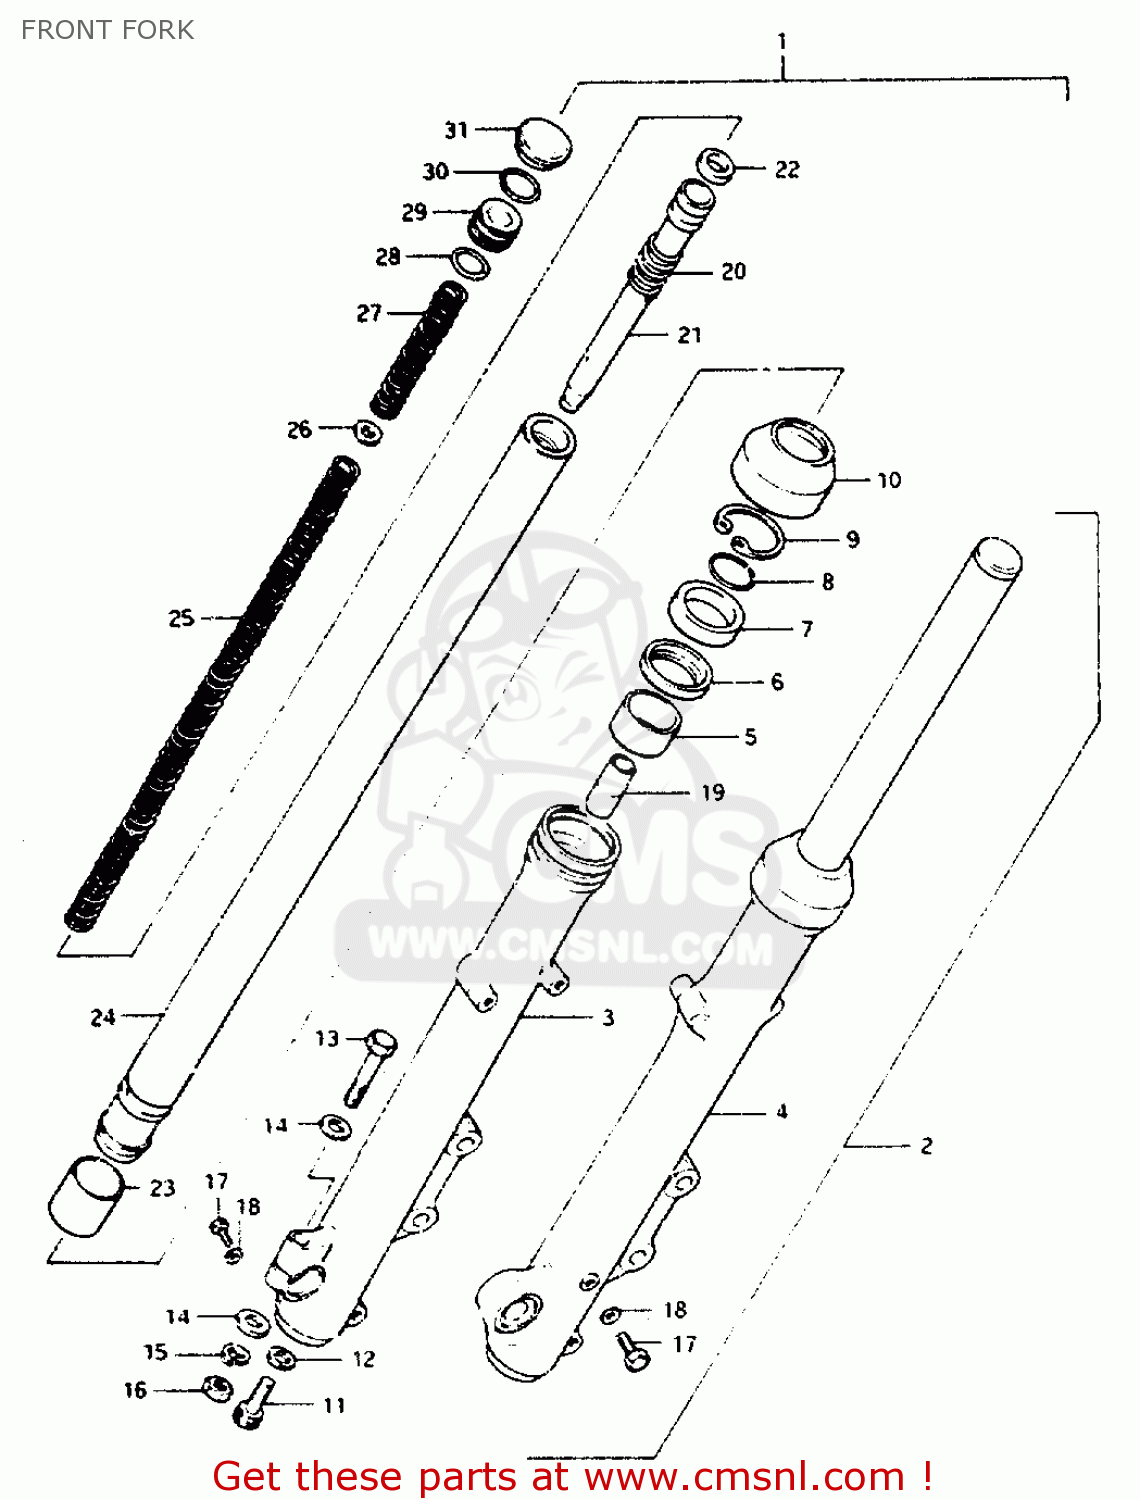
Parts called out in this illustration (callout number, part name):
1	DUMPER ASSY, RH
2	DUMPER ASSY, LH
3	TUBE,FORK,OUTER,RIGHT
4	TUBE,FORK,LEFT,OUTER
5	BUSH,GUIDE
6	SPACER,SEAL
7	OIL SEAL,FRONT FORK
8	RING,FR FORK
9	CIRCLIP,FORK OIL SEAL
10	BOOT
11	BOLT(8X27)
12	GASKET (NAS)
13	BOLT 8X50
14	WASHER
15	LOCK WASHER
16	NUT
17	BOLT(6X8)
18	GASKET,DRAIN,PLUG (NAS)
19	PIECE,OIL LOCK
20	SPRING,FORK REBOUND
21	CYLINDER,FRONT FORK
22	RING
23	PISTON
24	TUBE,FORK,INNER
25	SPRING B
26	WASHER,SPRING
27	SPRING,FRONT FORK,UPPER
28	O-RING
29	SPRING SEAT B
30	RING,STOPPER
31	CAP
